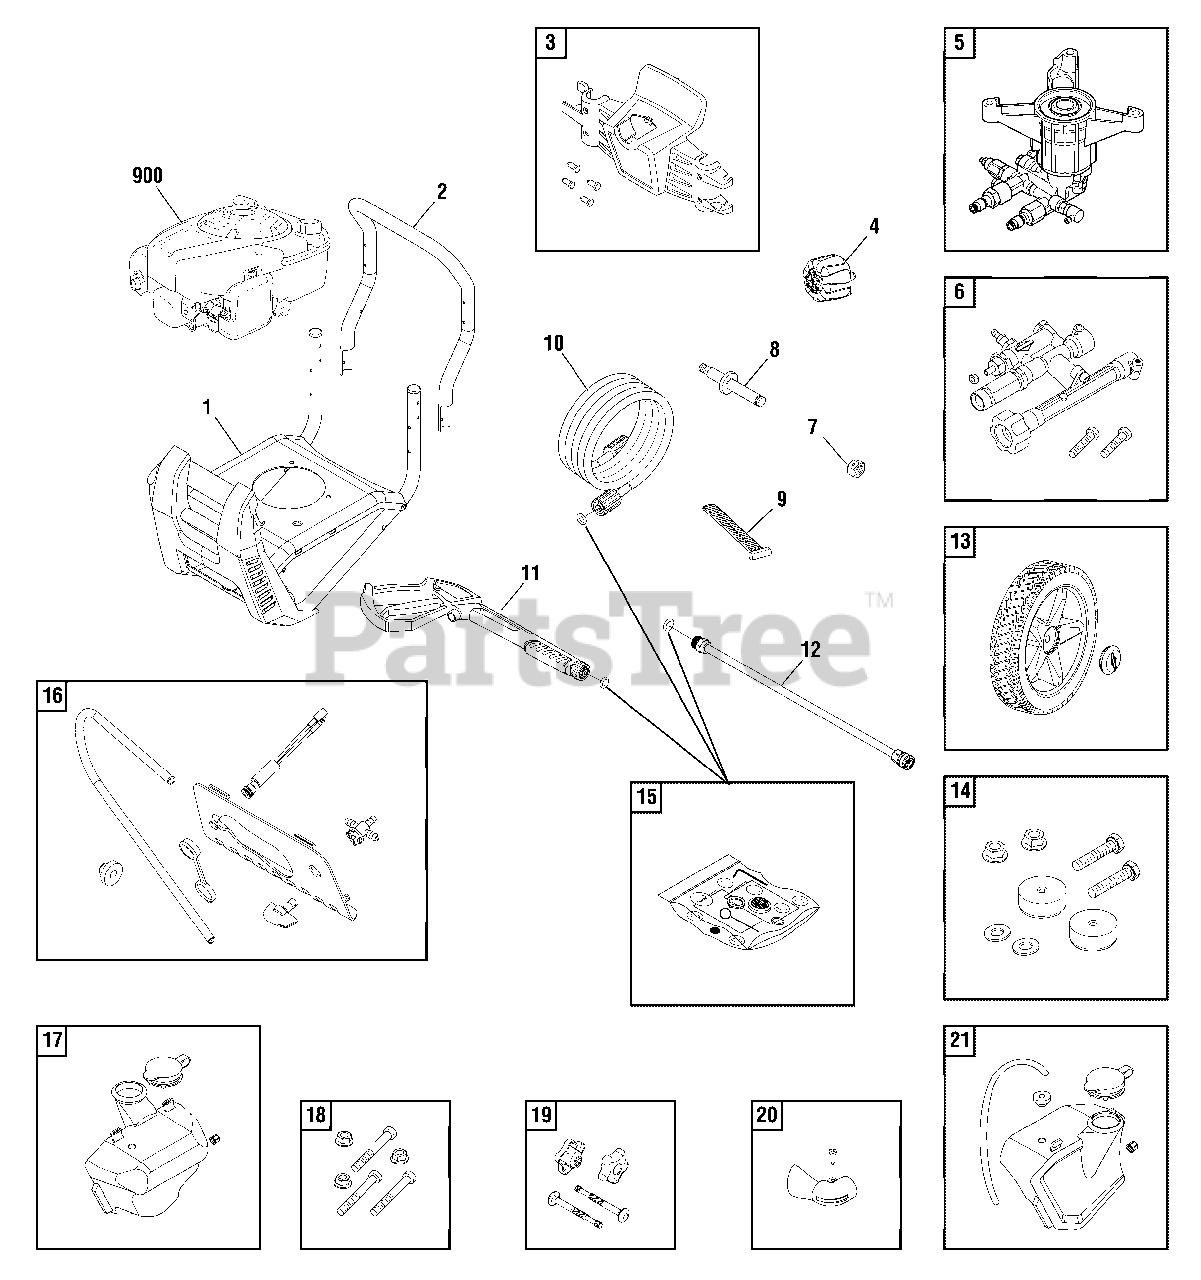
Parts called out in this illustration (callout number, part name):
6	POWERFLOW
10	HOSE
11	GUN
12	EXTENSION-QC
14	MOUNT-VIBRATION
16	PANEL-FRONT ASSY
17	TANK-CHEMICAL, LH
18	KIT-HARDWARE PUMP MOUNTING
19	KIT-HARDWARE HANDLE
20	DEFLECTOR-EXHAUST
21	TANK-CHEMICAL, RH
900	** ENGINE
